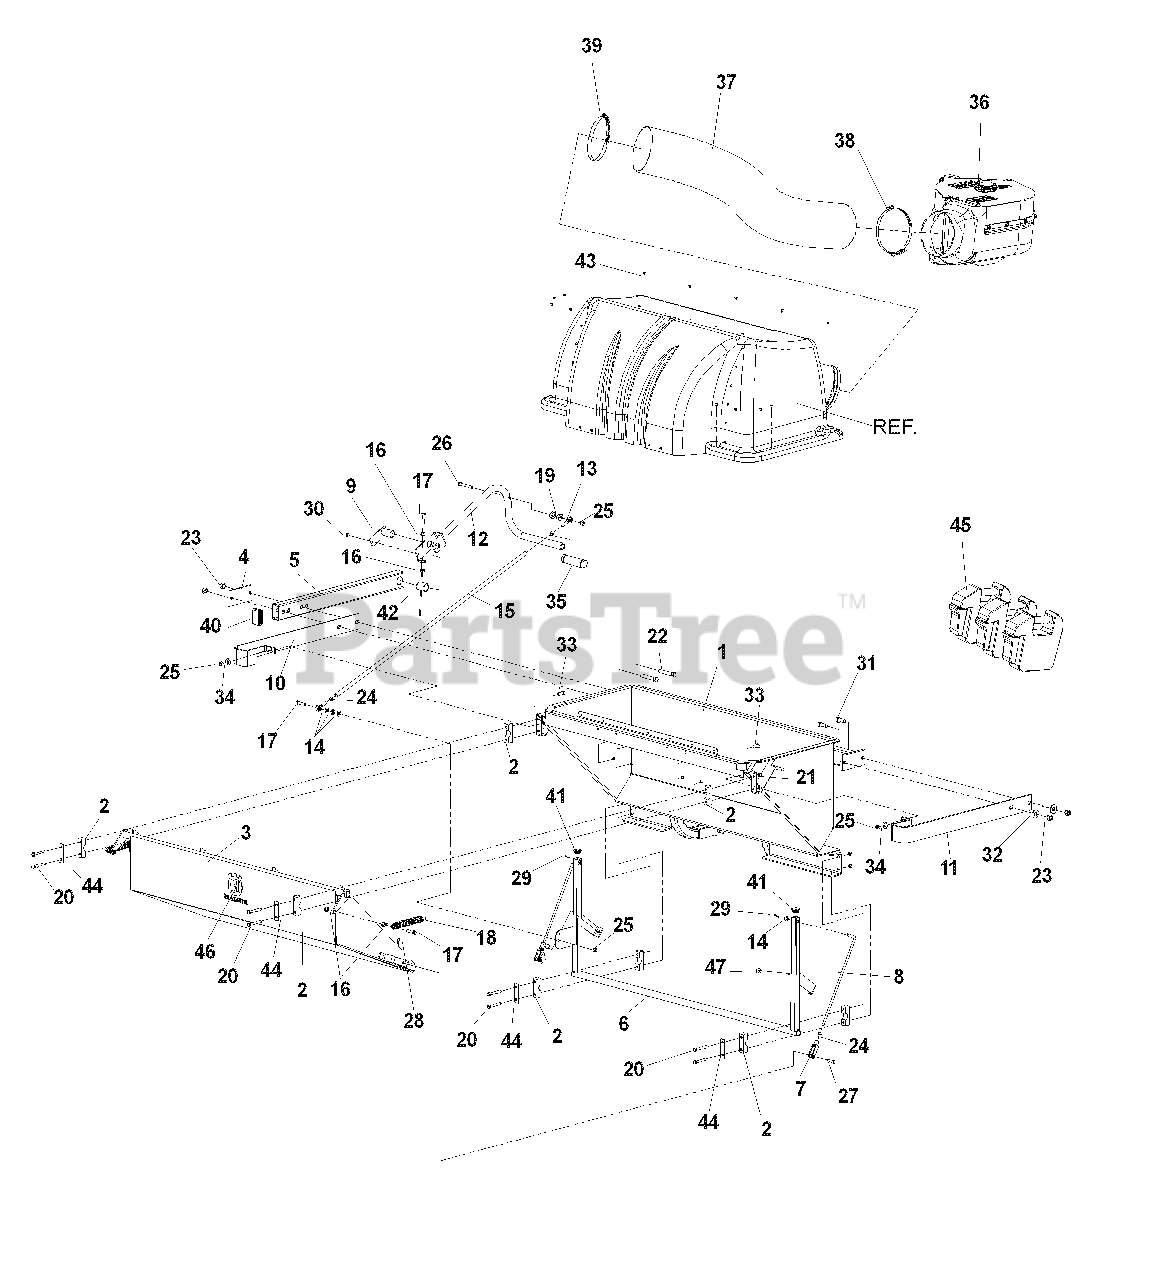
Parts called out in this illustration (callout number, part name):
2	PILLOW BLOCK
4	PLATE-BACKING
5	TUBE, SUPPORT, HANDLE
6	BELL CRANK
7	YOKE, 3/8F
9	PIN, PIVOT
10	GUARD, LEFT
11	GUARD, RIGHT
13	RODEND, 3/8-24, RH
14	WASHER, 3/8, SAE
15	TUBE, THREADED
16	NUT, 3/8-16 ,WHIZLK
17	HCS, 3/8-16x1 1/2
20	HCS, 5/16-18x2 1/2
21	NUT, 5/16-18, NYLOC
22	HCS, 1/2-13x3
23	NUT, 1/2-13, NYLOC
24	NUT,3/8-24,JAM
25	NUT, 3/8-16, NYLOC
26	HCS, 3/8-16x2 3/4
27	PINCLEVIS, 3/8x1 1/4
28	HAIRPIN COTTER
29	PIN, COTTER, 1/8x3/4
30	SCREW, 1/4Cx3/8
31	HCS, 1/2-13x1 1/4
32	WASHER, 1/2
33	HCS, 3/8-16x1
34	WASHER, 3/8
35	GRIP, HANDLE
36	BLOWER
38	OVER CENTER BAND
39	HOSE CLAMP, 6"-7"
40	PLUG, RECTANGULRTUBING
41	PLUG, SQUARETUBE
42	BUSHING, 1"
43	RIVET, STAVEX
44	REINFORCE ENT BAR
45	WEIGHTCAST, FRONT
46	DECAL, CROWN
47	GROMMET, BUMPER
